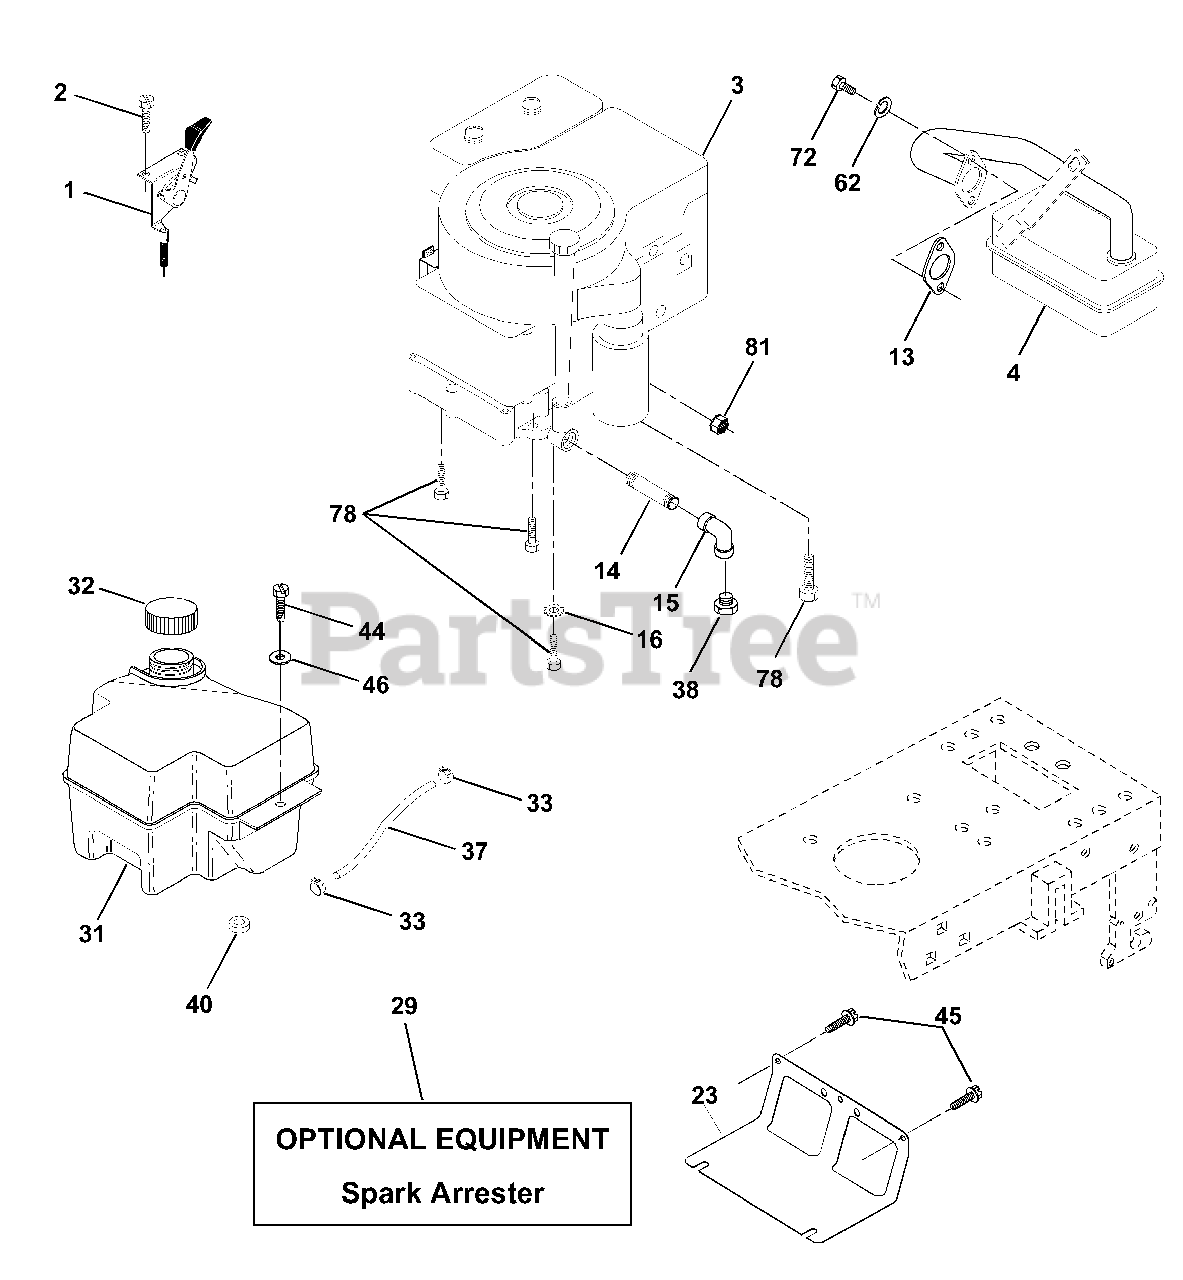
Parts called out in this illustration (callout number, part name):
1	Control Throt /Ch 23.5 Lh Flag
2	Screw Hex Thd Cut 1/4-20x5/8 T
4	Muffler Exhaust B&S Lt
13	Gasket 1 313 Id Tin Plated
14	Nipple Pipe 3/8 Npt X 3"
15	Elbow Std 90 Degree 3/8-18 Npt
16	Washer Lock Ext Tooth 3/8
23	Shield Browning/Debris Guard
29	Arrestor Spark
31	Tank Fuel 2 00 Fr
32	Cap Asm Fuel W/sym Vented
33	Clamp Hose Blk
37	Line Fuel 20"
38	Plug Oil Drain
40	Bushing Snap Nyl Blk Fuel Line
44	Screw Hexwsh Thdrol 1/4-20x3/4
45	Screw Hex Wsh Thdrol 3/8-16
46	Washer 9/32 X 7/8 X 16ga
62	Washer Lock Hvy Hlcl Spr 5/16
72	Screw Hexhd Cap 5/16-18x3/4
78	Screw Thdrol 3/8-16x1-1/4
81	Nut Keps Hex 1/4-20 Unc
